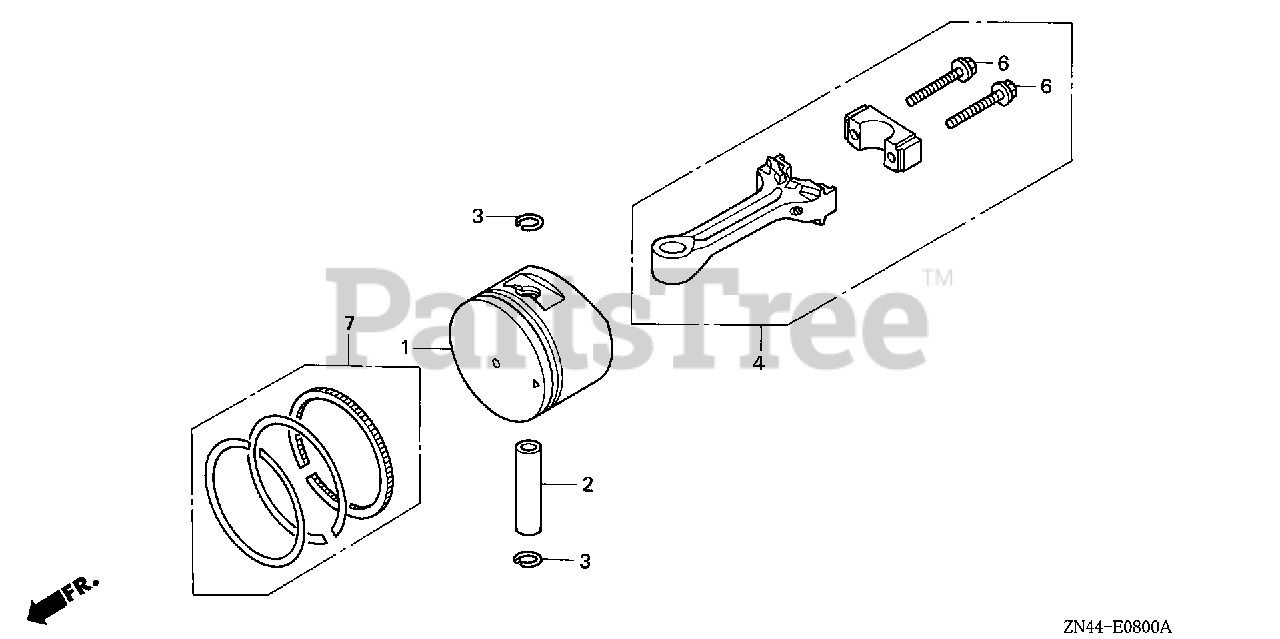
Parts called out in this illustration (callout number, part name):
1	PISTON (STD)
1	PISTON
2	PIN, PISTON
3	CLIP, PISTON PIN (10MM)
4	ROD ASSY., CONNECTING
6	BOLT, CONNECTING ROD
7	RING SET, PISTON (STD)
